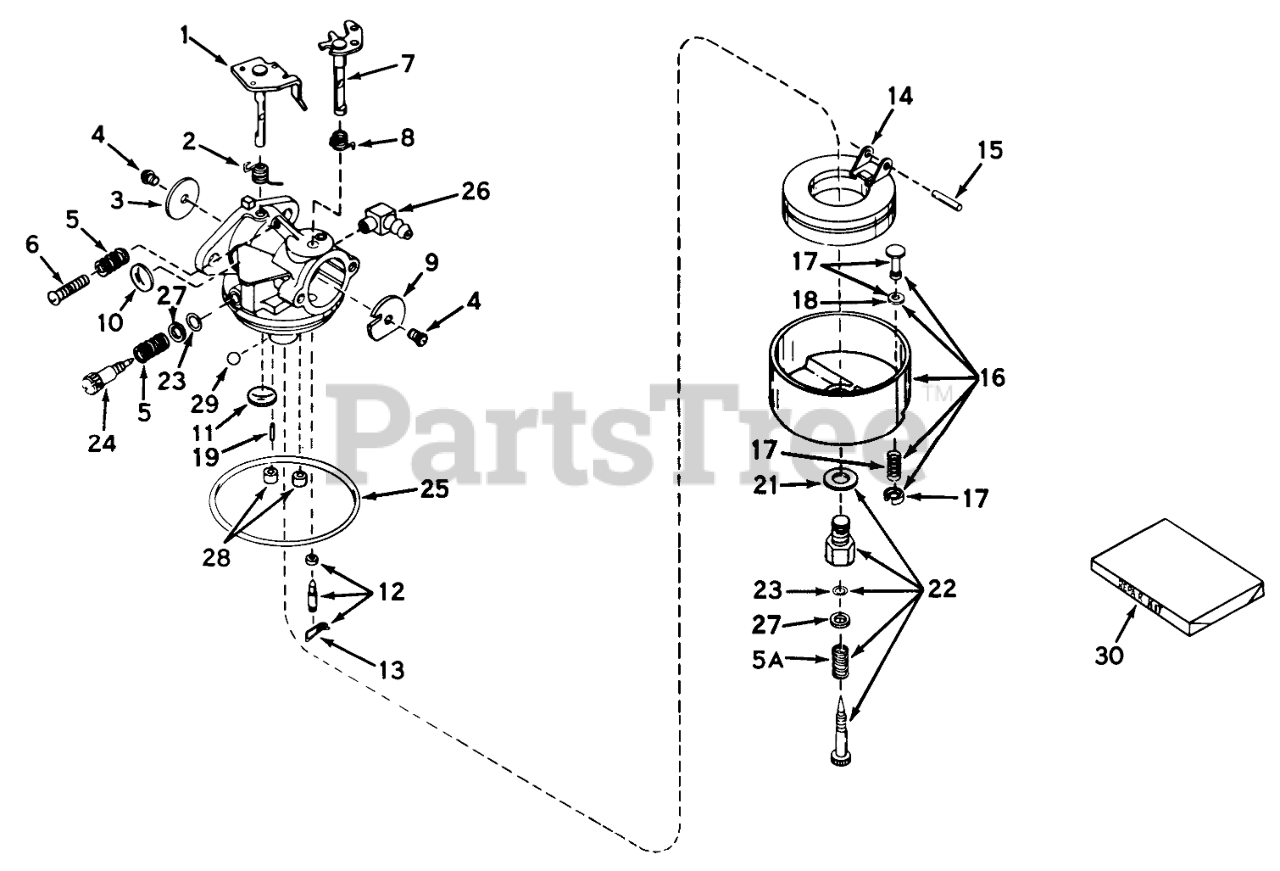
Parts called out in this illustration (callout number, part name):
1	Shaft & Lever Assy.
2	Spring, Throtte Return
3	Shutter-Throttle
4	Screw-Shutter
5	Spring-Tension
6	Screw-Throttle Crack Screw / Idle Speed
7	Shaft& Lever Assy., Choke
8	Spring, Choke return
9	Shutter, Choke
10	Plug-Welch, Idle Mixture Well
11	Plug-Welch, Atmospheric Vent
12	Inlet Needle, Seat & Clip Assy. (Incl. No. 13)
13	Clip-Spring
14	Float,Carburetor
15	Shaft-Float
16	Bowl & Drain Assy., Float (Incl. No. 17)
17	Plunger Assy., Drain (Incl. No. 18)
18	Gasket-Plunger, Drain
21	Washer-Bowl Nut
22	Adjustment Screw Assy., Main (Incl. Nos. 5A, 21, 23 & 27)
23	"O"Ring
24	Screw, Idle Adj.
25	O Ring-Bowl, Float
26	Fitting Fuel Inlet
28	Plug, Cup
29	BalI, Steel
30	Repair Kit
